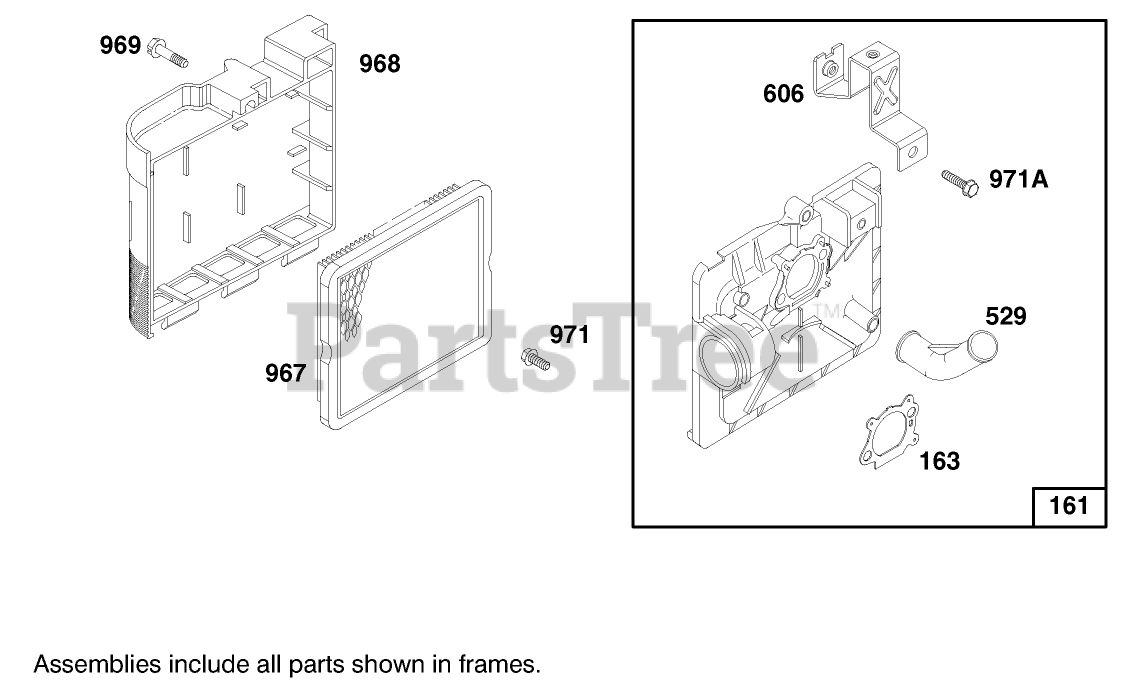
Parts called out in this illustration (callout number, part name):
161	Base-Primer, Air Cleaner
163	Gasket-Cleaner, Air
529	Grommet
606	Strap-Bracket
967	Filter-Air Cleaner, Cartridge
968	Air Cleaner Cover
969	Screw(A/C Cover)
971	Screw-Hex.
971A	Screw-Hex.
